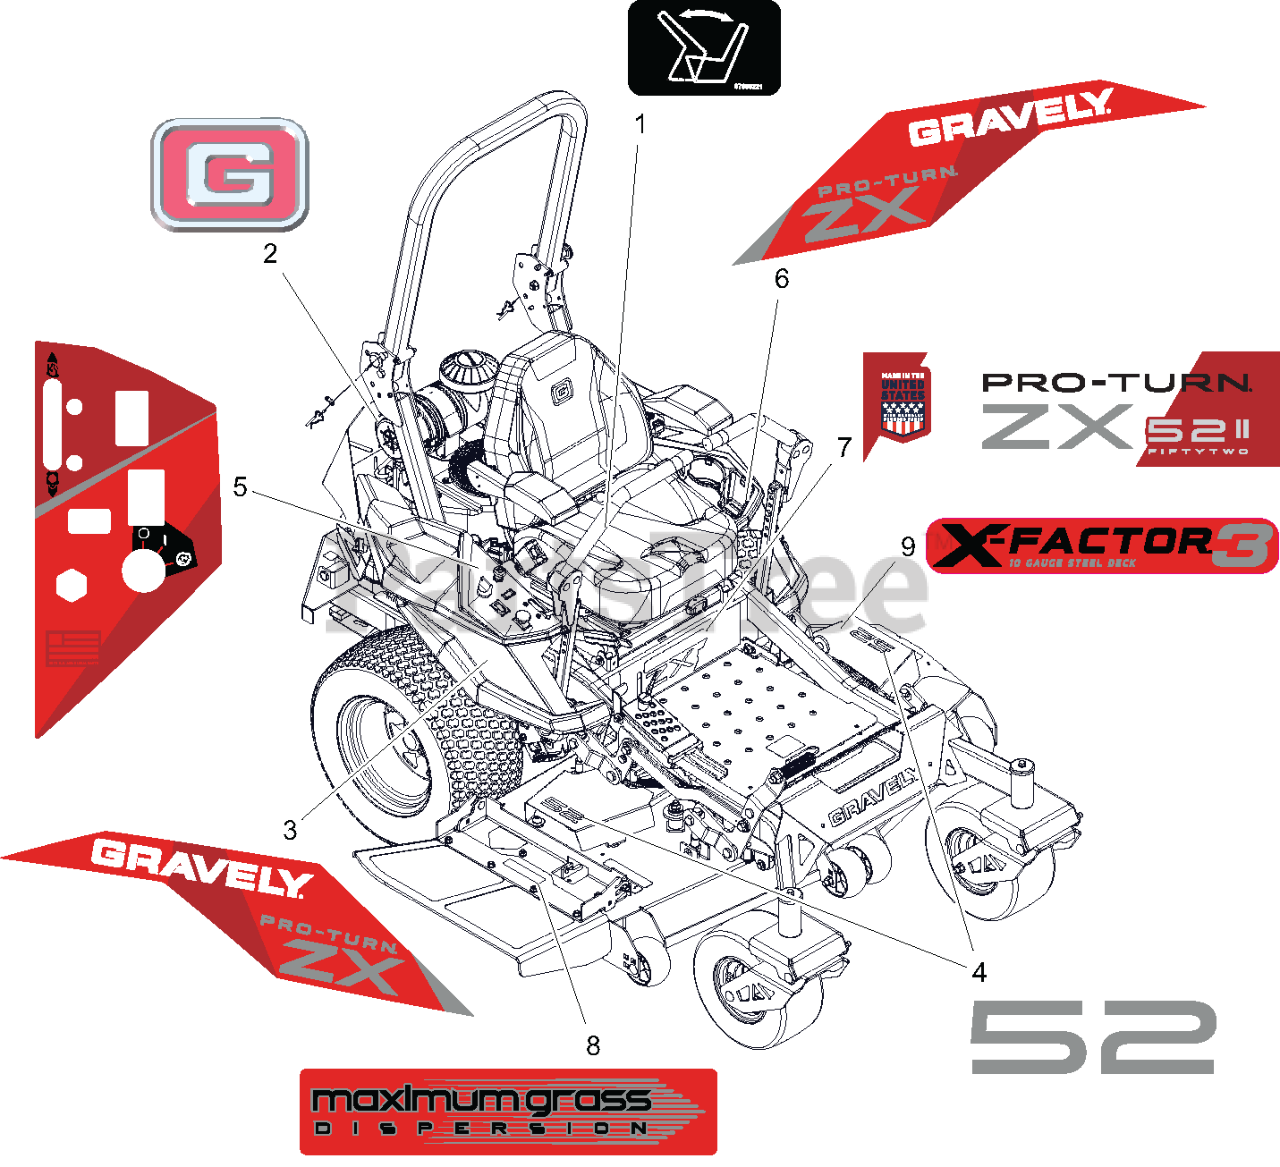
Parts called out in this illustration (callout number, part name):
1	DECAL - SEAT RELEASE
1	DECAL, GRAVELY BRAND
1	DECAL, FENDER RH - PTZX
1	DECAL, CONTROL PANEL
1	DECAL, FENDER LH - PTZX
1	DECAL, PTZX - 52
1	DECAL, DECK - MAX GRASS
1	DECAL, X-FACTOR 3
2	DECAL, DECK - 52
